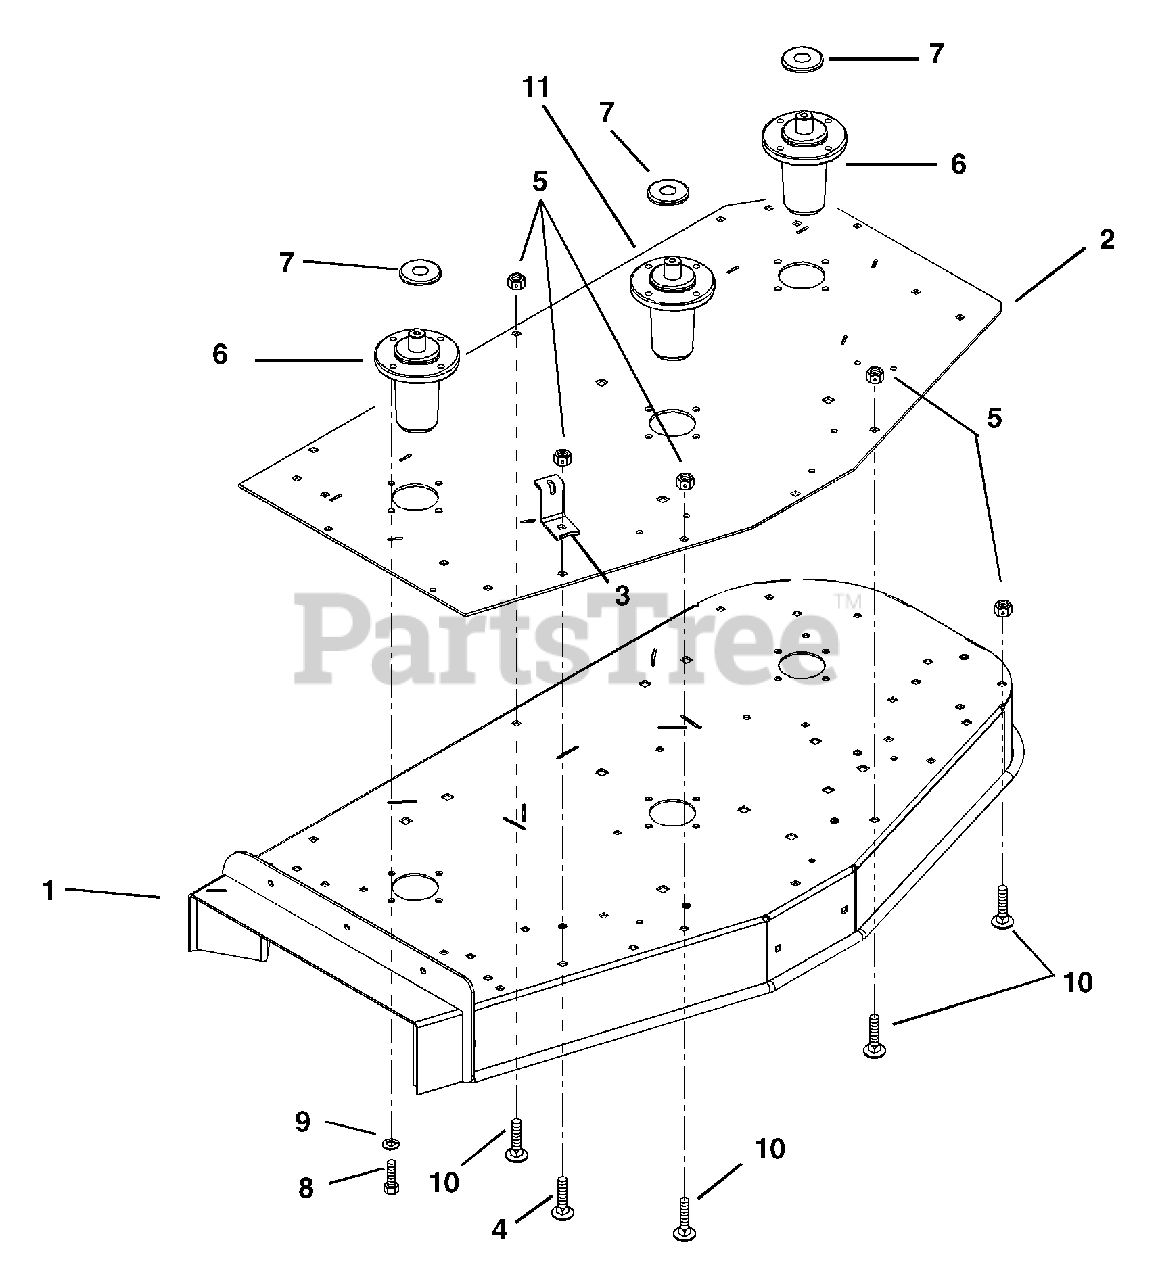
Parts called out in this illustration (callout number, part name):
1	Weldment, 50"Deck
2	Plate, 50" Reinforcement
3	Anchor, Spring
4	Bolt-Round Head Square Neck .38 - 16 x 1.25 Grade 2
5	Nut-Locking-Nylon .38 - 16
6	Assembly, Spindle L-Hub
7	Slinger-Dust
8	Bolt-Hex .38 - 16 x 1.00 Grade 5
9	Washer-Locking .38 x .094
10	Bolt-Round Head Square Neck .38 - 16 x 1.00 Grade 2
11	Spindle Assembly (Center)
